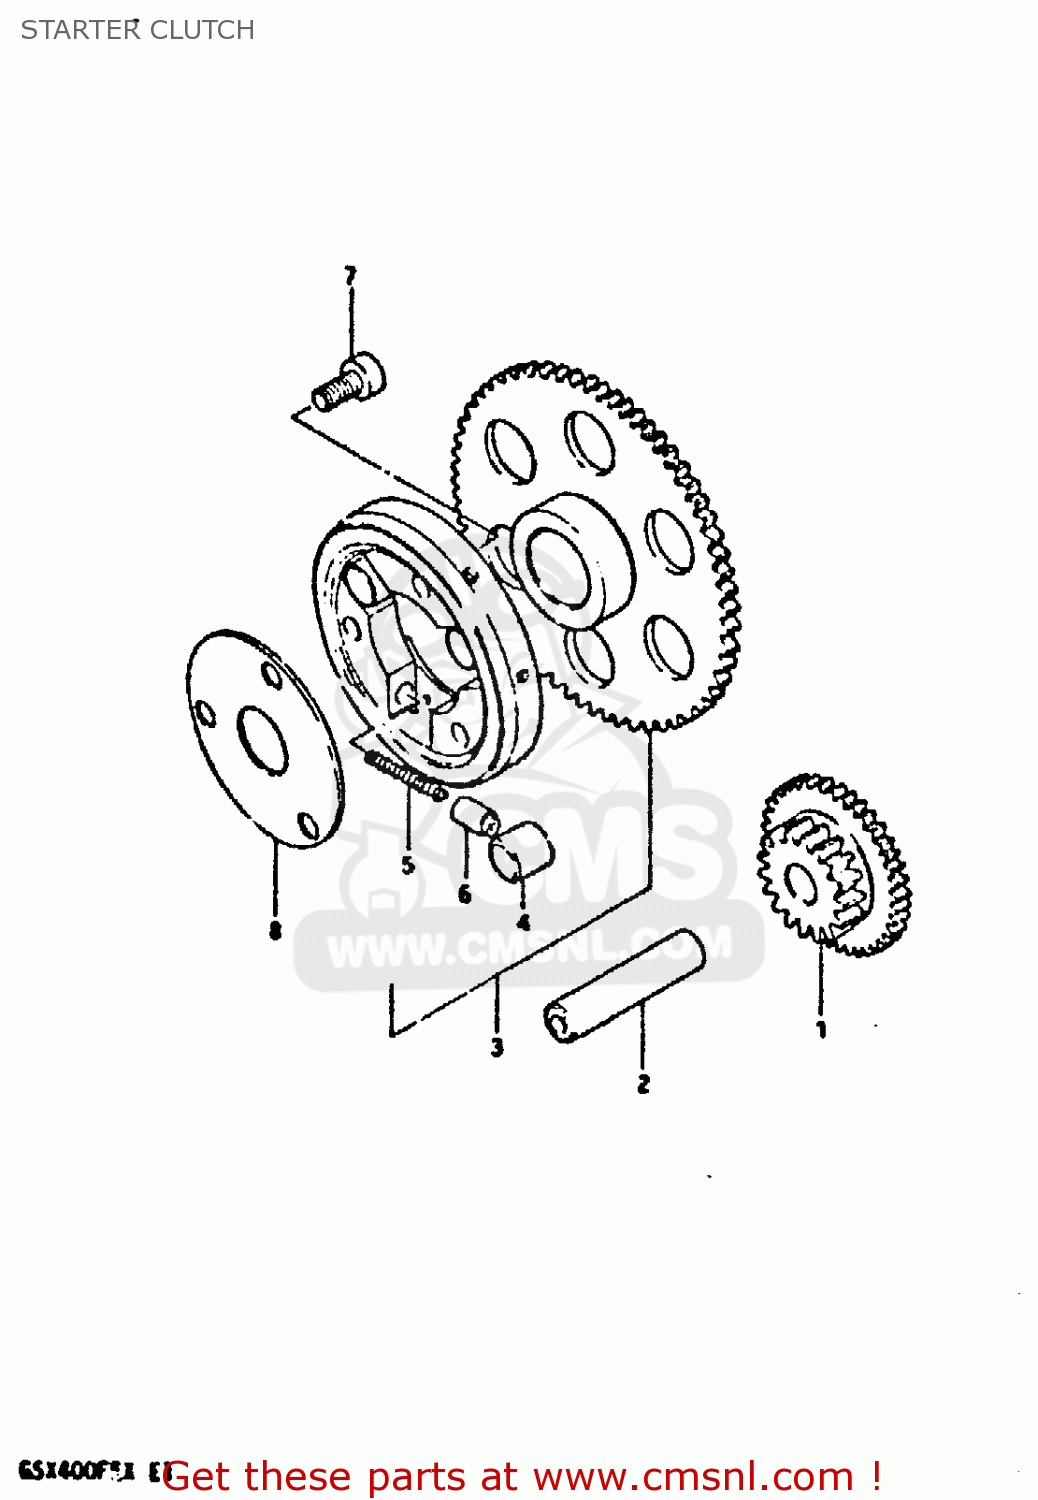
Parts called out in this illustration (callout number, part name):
1	GEAR, STARTER IDLE (NT:47/18)
2	PIN(7.4X13X40)
3	STARTER CLUTCH SET
4	ROLLER(15X13)
5	SPRING
6	PIECE,PUSH
7	BOLT
8	SHIM,STARTER CLUTCH HUB
